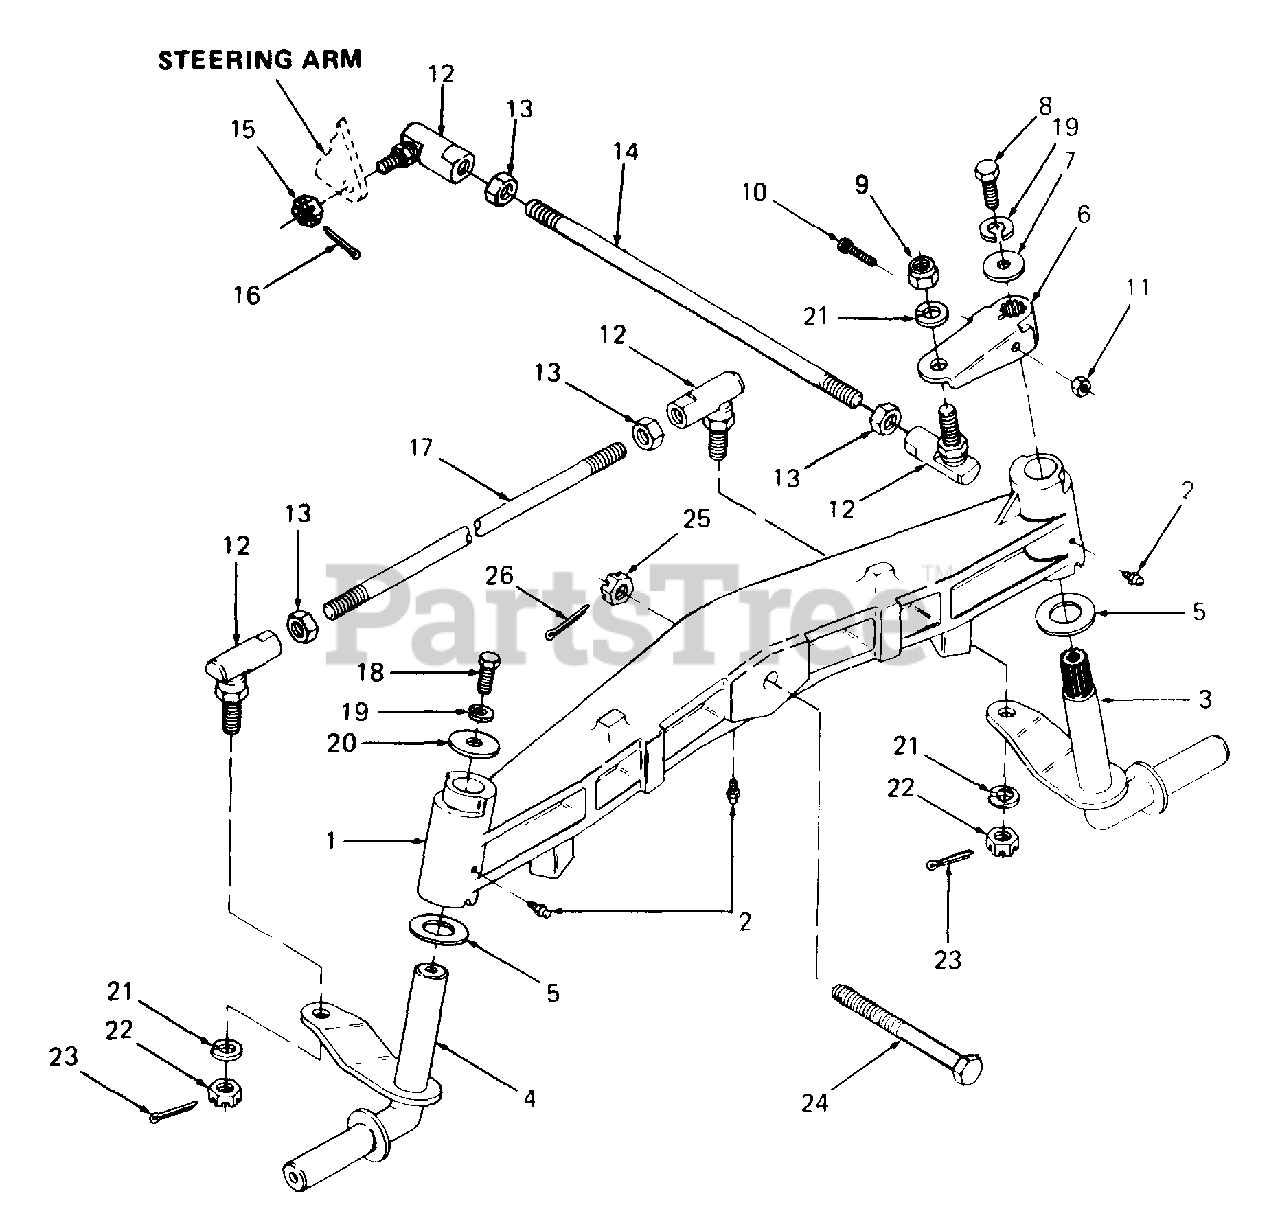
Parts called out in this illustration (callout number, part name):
3	Knuckle, Steering - LH
4	Knuckle, Steering - RH
5	Washer, Thrust, 1.03 X 1.62 X .03 Thk HDN
6	Arm, Steering
7	Washer, Flat, .406 X 1.25 X .157 Thk
8	Screw, Hex Cap, 3/8-24 X 1.0 Lg
9	Nut, Hex Top Lock, 1/2-20
10	Screw, Socket Hd Cap, 1/4-20 X 1.38 Lg
11	Nut, Hex Patch Lock, 1/4-20
12	Ball Joint
13	Nut, Hex Jam, 1/2-20 GR5
14	Link, Drag
15	Nut, Hex Castle, 1/2-20 GR5
16	Pin, Cotter, 3/32 Dia X 1.25 Lg
18	Screw, Hex Cap, 3/8-24 X 1.0 Lg
19	Washer, Lock, 3/8
20	Washer, Flat, .406 X 1.5 X .12 Thk
21	Washer, Lock, 1/2
22	Nut, Hex Castle, 1/2-20 GR5
23	Pin, Cotter, 3/32 Dia X 1.25 Lg
24	Bolt, Hex, 3/4-10 X 5.25 Lg GR5
25	Nut, Hex Castle, 3/4-10
26	Pin, Cotter, 1/8 Dia X 1.5 Lg
